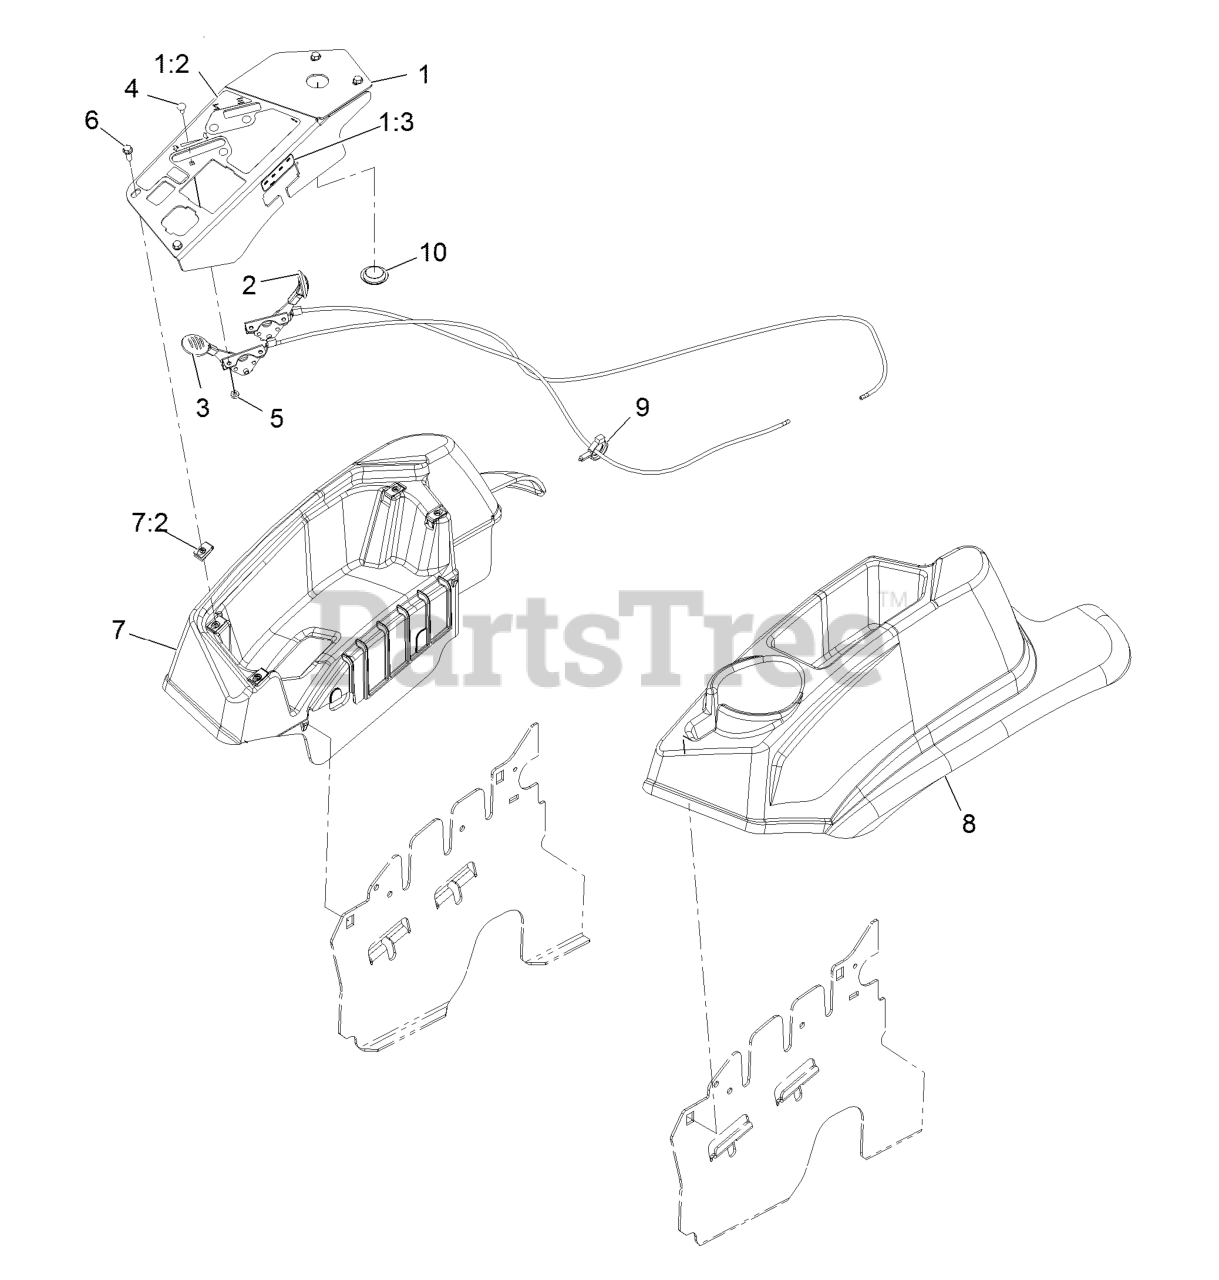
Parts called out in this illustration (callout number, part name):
1	CONSOLE,PANEL W/DECAL
1:2	DECAL-CONTROL PANEL
1:3	DECAL-FUSE
2	ASM, CHOKE CABLE
3	ASM,THROTTLE CABLE
4	BOLT-CARR
5	NUT-LOCK, NI
6	SCREW-HWH
7	CONSOLE,RH AS ASM
7:2	Nut-Retainer-Panel 1/4-20
8	CONSOLE, LH AS
9	CLAMP-HOSE
10	PLUG-PLASTIC
